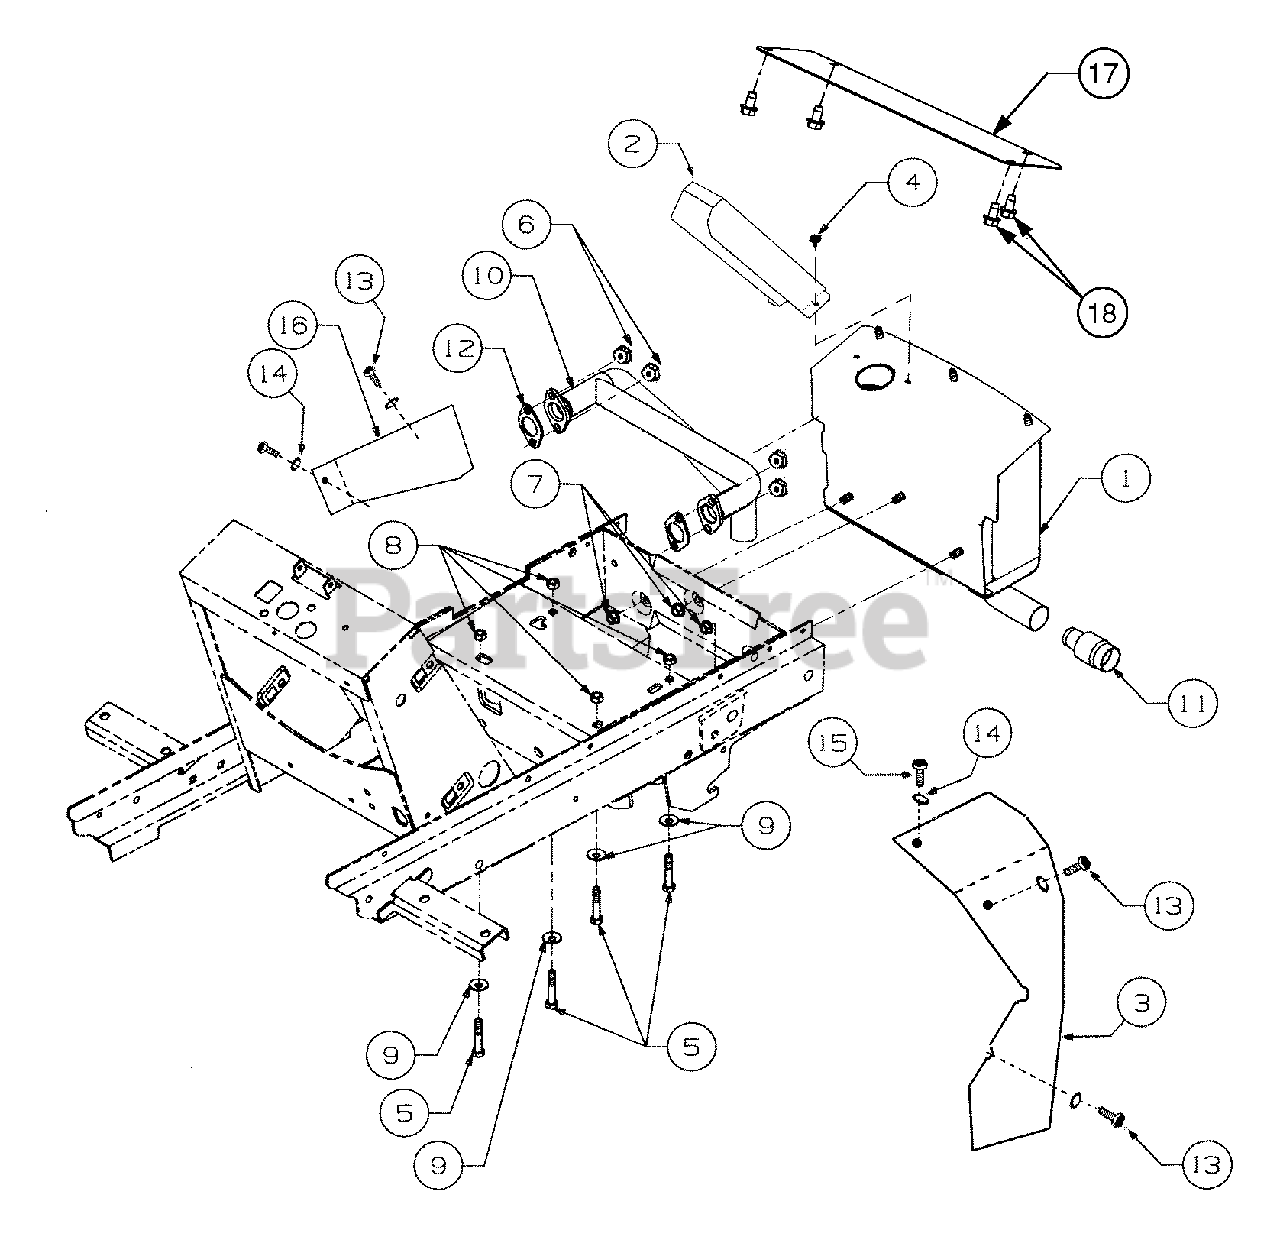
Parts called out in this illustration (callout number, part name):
1	Muffler Assembly
2	Shield, Muffler Tube
5	Bolt, Eng Mount, 3/8-24 x 1.75 GR5
6	Nut, Hex Flange
7	Nut, Hex Flange Lock, 5/16-18
8	Nut, Hex Lock, 3/8-24
9	Washer, Bell, .380 x .88 x .062
10	Tube, Exhaust
11	Arrestor, Spark
12	Gasket, Exhaust
13	Screw, Hex Cap, M6 x 1 x 10
14	Washer, Flat, .281 x .5 x .06
15	Screw, Truss Hd Tapp, #10 x .5
18	Screw, Hex Wsh. Hd. Tapp. 1/4-20 x .5
